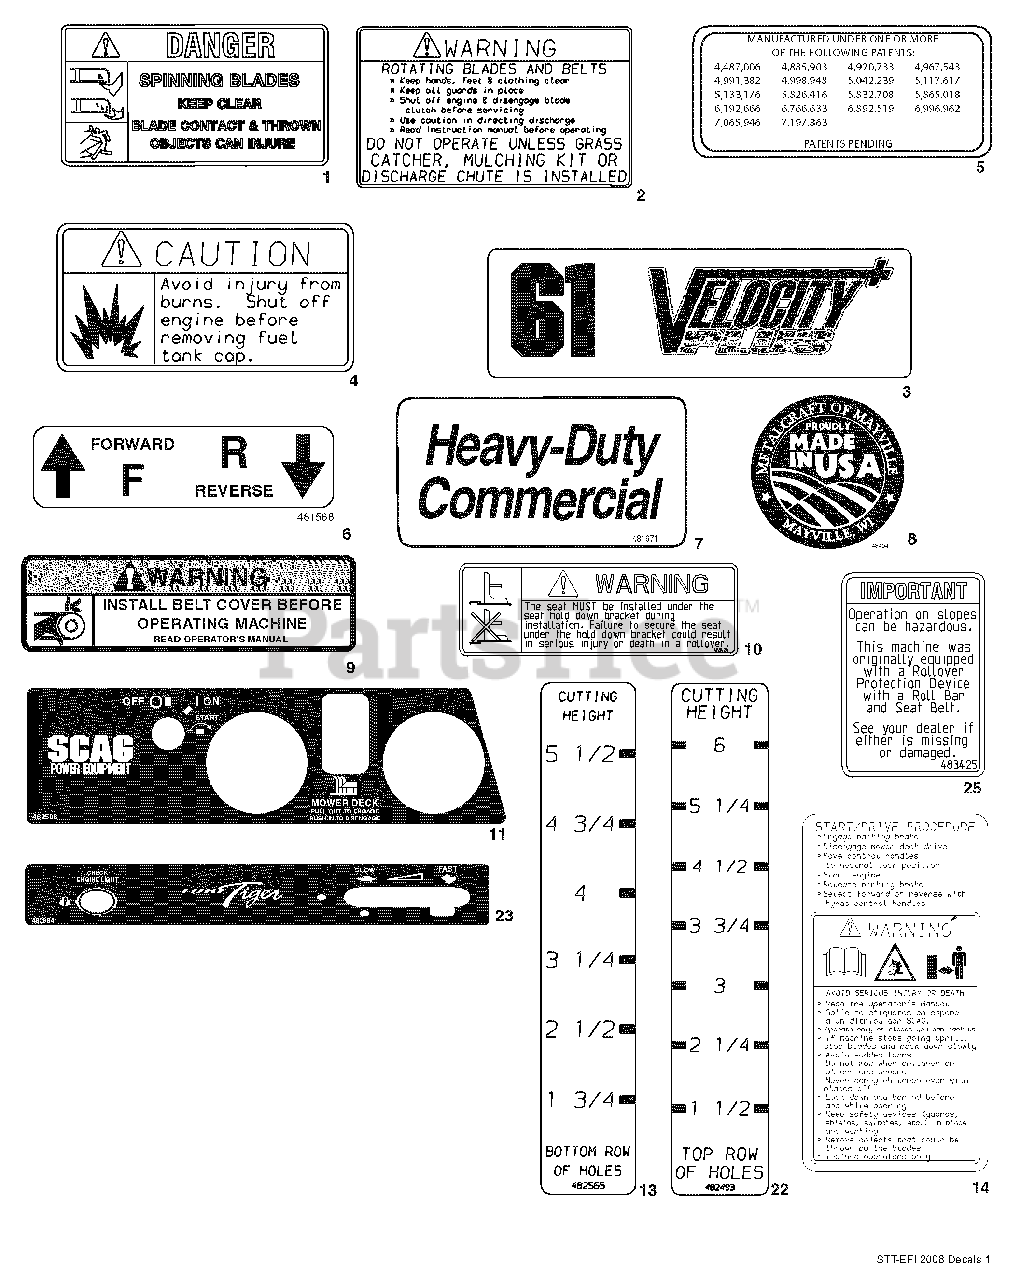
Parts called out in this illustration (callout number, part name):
1	Decal, Danger-Spinning Blades
2	Decal, Warning-Rotating Blades
3	Decal, 61 Velocity Plus
4	Decal, Fuel Tank
5	Decal, Patents
6	Decal, Traction Control
7	Decal, Heavy Duty Commercial
8	Decal, Metalcraft-Made In USA
9	Decal, Belt Cover
10	Decal, Warning Seat Hold Down
11	Decal, Instrument Panel-Upper
13	Decal, Cutting Height - Lower
14	Decal, Start/Drive Procedure
22	Decal, Cutting Height - Upper
23	Decal, Instrument Panel - Lower
25	Decal, ROPS
